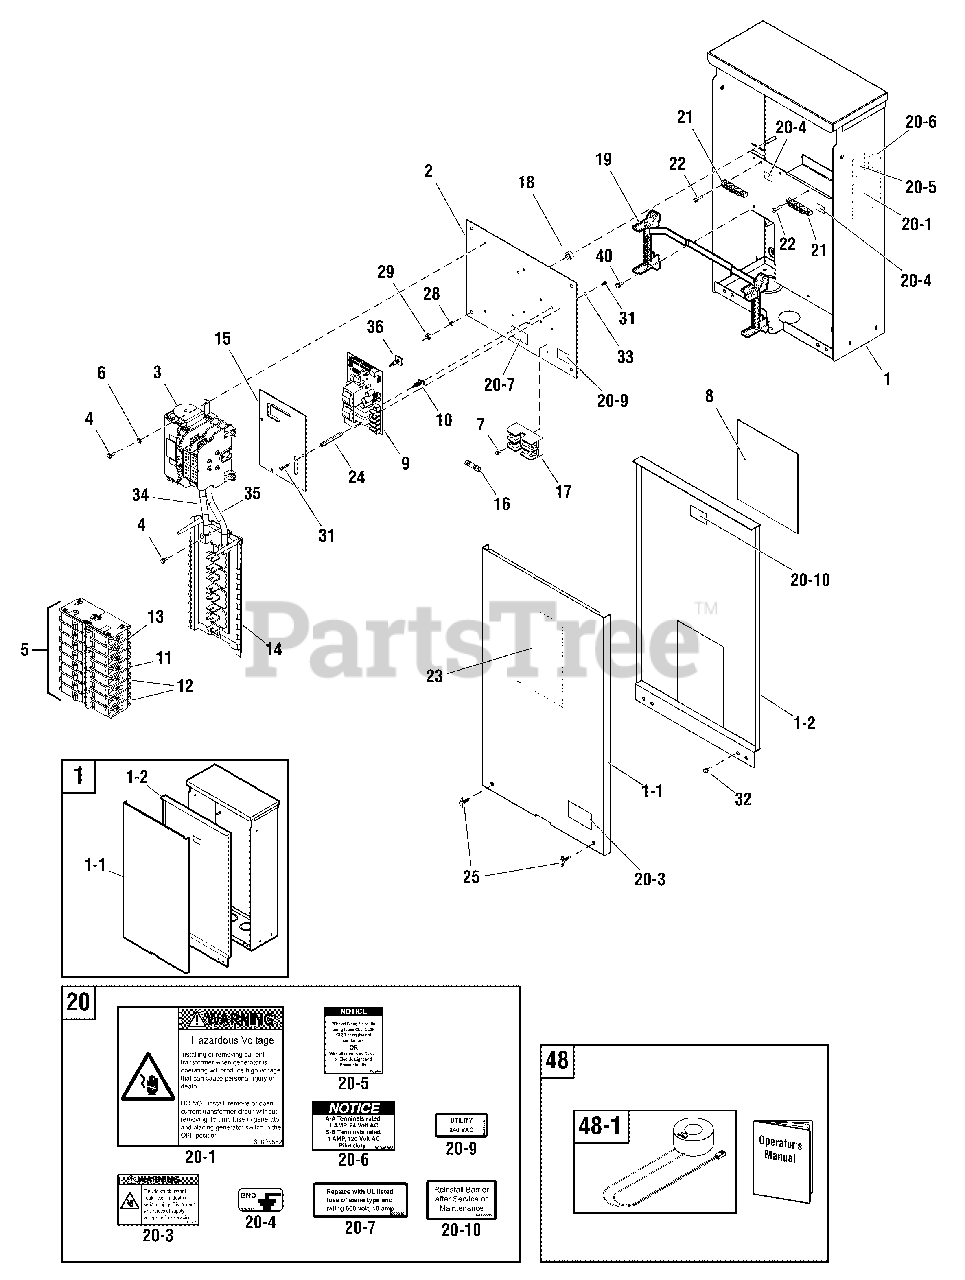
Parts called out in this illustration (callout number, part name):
1	ENCLOSURE
2	BACK PANEL
3	SWITCH, Transfer
4	* TRILOBULAR, #10-32 x 1/2
5	BREAKER, Circuit, 20A
6	* WASHER, External Tooth, #10
7	* SCREW, Hex Head, Trilobular, #6-32 x 3/8
9	BOARD, Circuit
11	BREAKER, Circuit, 40A
12	BREAKER, Circuit, 50A
13	BREAKER, Circuit, 30A
18	SPACER
19	BLOCK, Neutral
20	DECAL SHEET - WARNINGS
20-1	DECAL, Warning Voltage
20-3	DECAL, Warning Shock
20-4	DECAL, Ground
20-5	DECAL, Notice
20-6	DECAL, Contacts Rated
20-7	DECAL, Fuse, 10 Amp
20-9	DECAL, Sensing, Utility
20-10	DECAL, Reinstall After
21	BAR, Ground
22	* TRILOBULAR, #10-32 x 3/4
28	* WASHER, Lock, 1/4
29	* NUT, 1/4-20
31	* SCREW, Phillips, 6-32 x 3/8
32	* TRILOBULAR, #10-32 x 3/8
33	* WASHER, Lock, #6
40	* TRILOBULAR, #10-31 x 3/4
